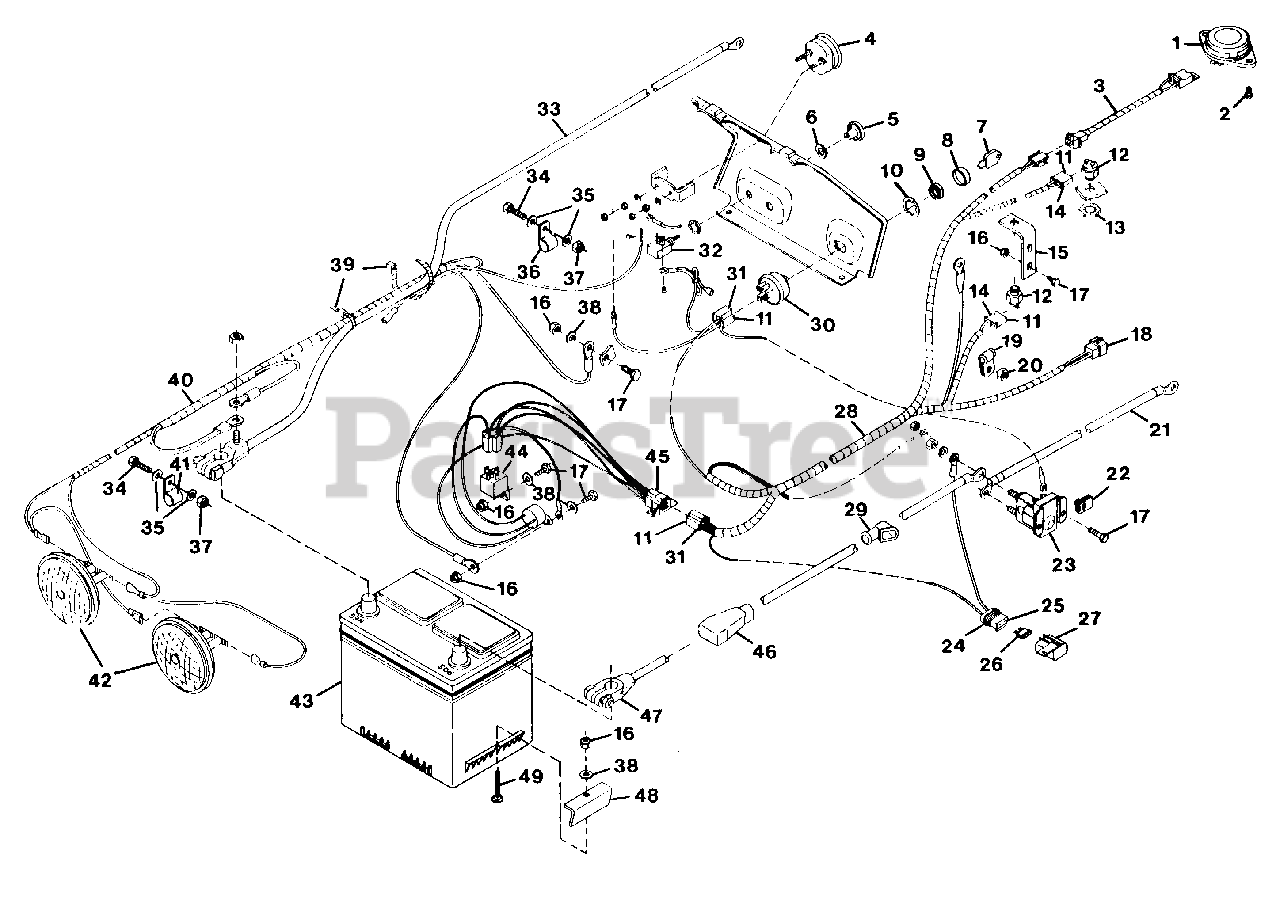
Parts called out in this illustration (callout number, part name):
1	SWITCH, SEAT
2	SCREW, MACHINE 1/4-20
3	HARNESS, WIRING SEAT SWITCH
4	GAUGE, AMMETER
5	KNOB, LIGHT SWITCH
6	NUT, SPECIAL LIGHT SWITCH
7	KEY, IGNITION SWITCH
8	BOOT, 9/16 SWITCH
9	NUT, JAM 9/16-24
10	WASHER, LOCK 9/16 INT. TOOTH
11	TERMINAL
12	SWITCH, INTERLOCK
13	NUT, STAMPED 9/16-18
14	CONNECTOR, 2-WIRE SWITCH
15	BRACKET, SWITCH
16	NUT, LOCK 1/4-20
17	BOLT, HEX 1/4-20X.75
18	CONNECTOR
19	CLAMP
20	NUT, LOCK 3/8-16
21	CABLE, STARTER
22	NUT, SPEED 1/4-20
23	SWITCH, MAGNETIC
24	CONNECTOR
25	TERMINAL, 14-16 GAUGE
26	FUSE, 25 AMP
27	COVER
28	HARNESS, WIRING
29	BOOT, BATTERY CABLE
30	SWITCH, IGNITION
31	CONNECTOR
32	SWITCH, LIGHT
33	CABLE, NEGATIVE BATTERY
34	BOLT, HEX 5/16-18X1.00
35	WASHER, FLAT .344X.688X.065
36	CLAMP, NYLON
37	NUT, LOCK 5/16-18
38	WASHER, FLAT .281X.625X.065
39	TIE, CABLE
40	HARNESS, WIRING GROUND AND LIGHT
41	CLAMP, NYLON
42	HEADLIGHT
43	BATTERY, 12 VOLT
44	RELAY
45	MODULE, TIME DELAY
46	COVER, BATTERY TERMINAL
47	CABLE, BATTERY TO MAGNETIC SWITCH
48	CLAMP
49	BOLT, 1/4-20X1.75 RD HD SQ NK
